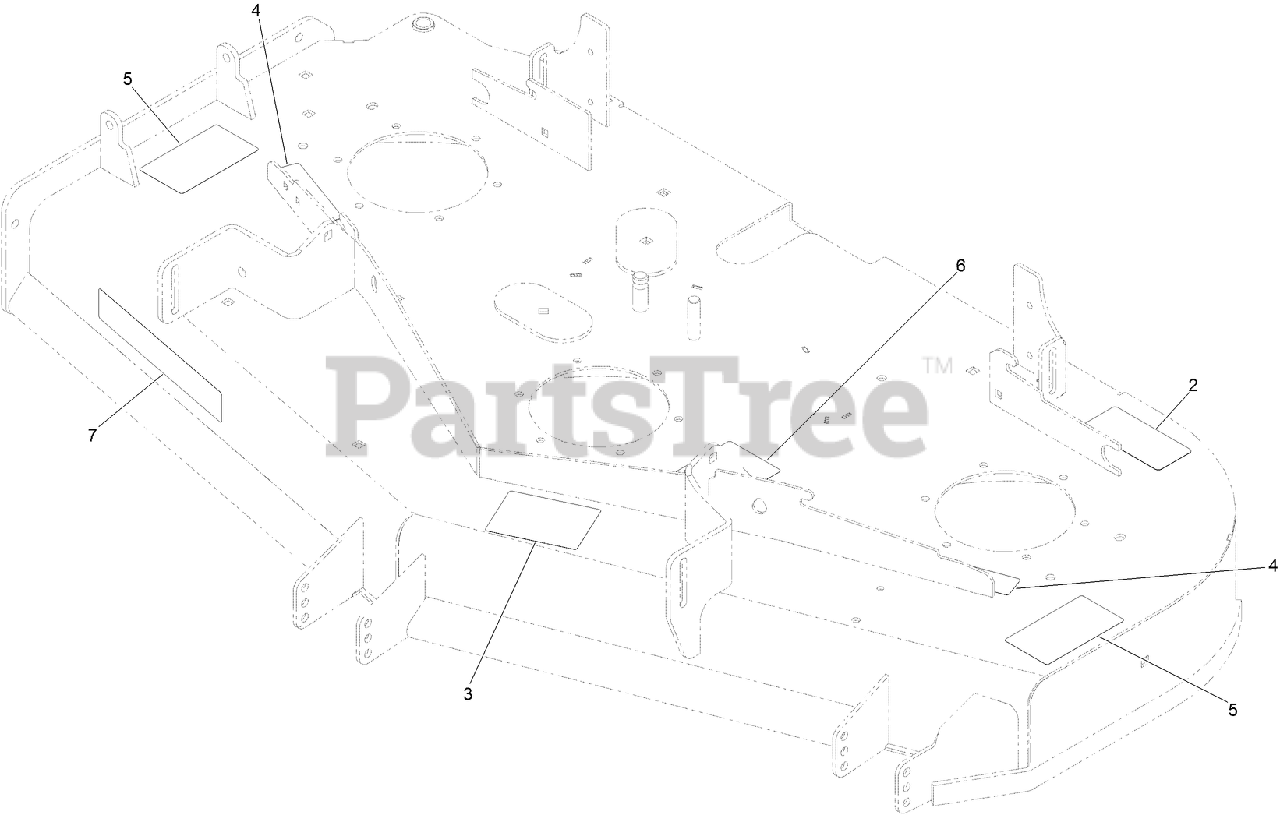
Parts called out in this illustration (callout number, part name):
2	DECAL-TORQUE, BLADE BOLT
3	DECAL-SCALP, ANTI
4	DECAL-COVER, MISSING
5	DECAL-DANGER
6	DECAL-ROUTING, BELT
